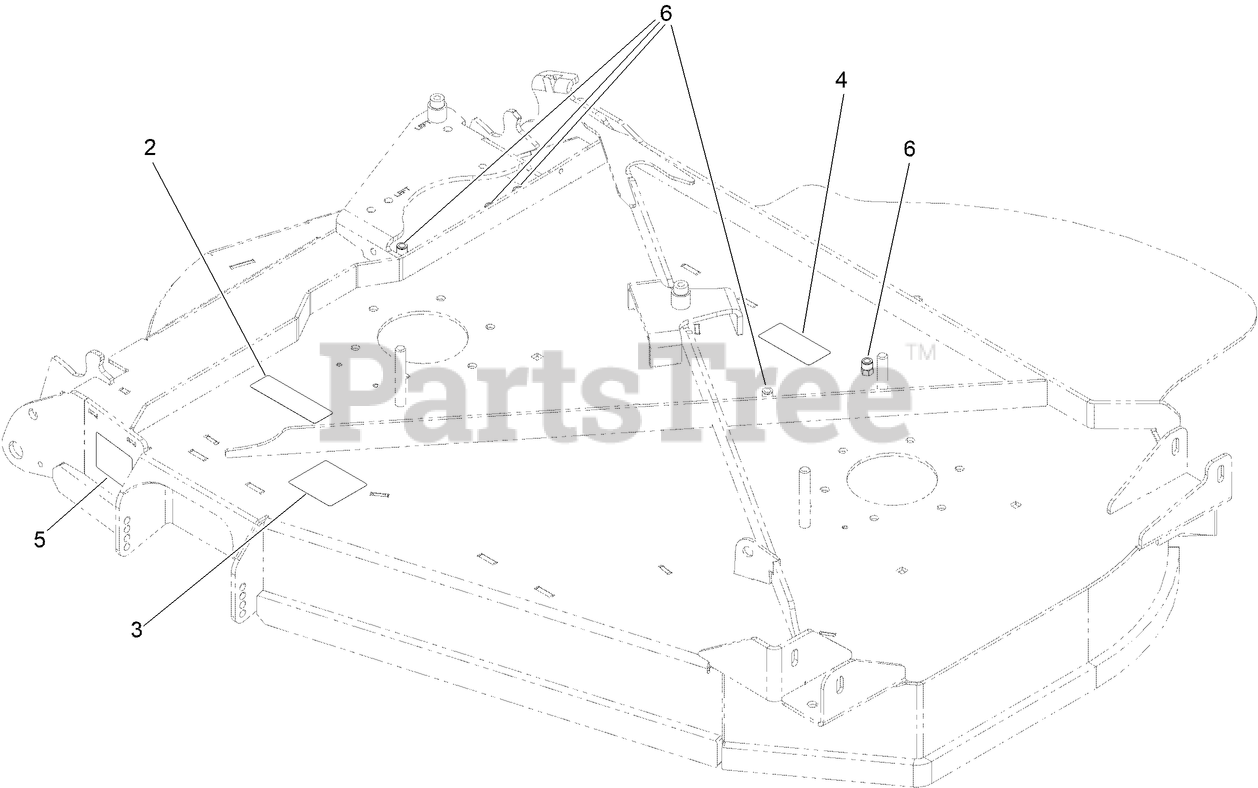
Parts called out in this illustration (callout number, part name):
2	DECAL-COVER, MISSING
3	DECAL-DANGER, THROWN OBJECT
4	DECAL-BOLT TORQUE
5	DECAL-WARNING, PINCH POINT
6	NUT-CLINCH,HEX
